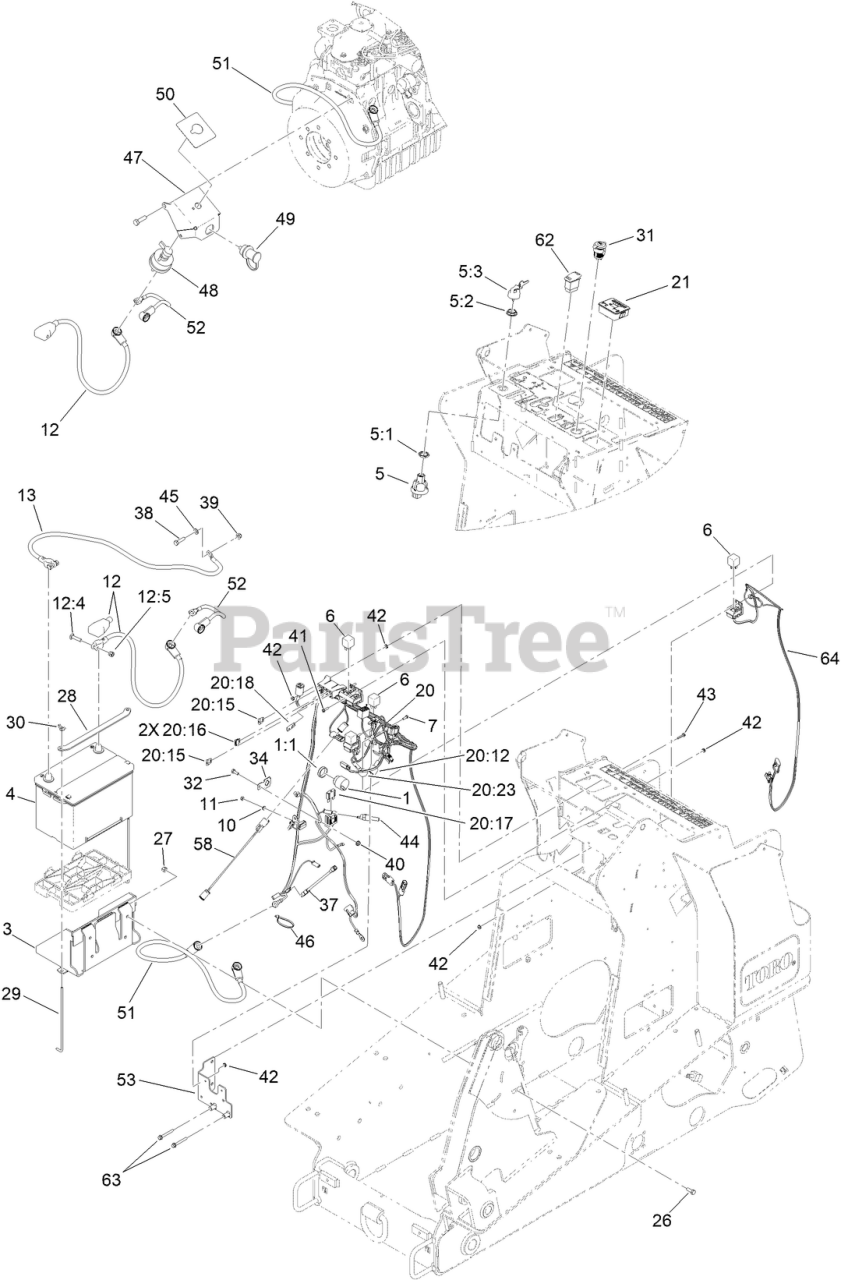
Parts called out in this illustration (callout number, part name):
1	AUDIO ALARM ASM
1:1	NUT-PLASTIC, KNURLED
3	TRAY-BATTERY
4	BATTERY
5	IGNITION SWITCH ASM
5:1	NUT-HEX
5:2	NUT-FACE, M22 (PLASTIC)
5:3	SET-KEY, IGNITION
10	WASHER-LOCK, SPRING
11	NUT-HEX
12	CABLE-BATTERY, POS ASM
12:4	BOLT-BATTERY CLAMP, 5/16-18 UNC
12:5	NUT-CLAMP, BATTERY
13	CABLE-NEGATIVE
20	HARNESS-WIRE, MAIN
20:15	FUSE-BLADE, 10 AMP
20:16	FUSE-BLADE, 15 AMP
20:17	FUSE-BLADE, 50 AMP
20:18	CAP-PLUG
21	MODULE-HOUR METER
26	SCREW-HH
27	NUT-LOCK, NI
28	STRAP-HOLD DOWN, BATTERY
29	ROD-HOLD DOWN, BATTERY
30	NUT-WING
31	RECEPTACLE-12V
32	SCREW-HH
34	CLIP-FUSE
37	HARNESS-LINK, FUSIBLE
38	SCREW-HH
39	NUT-HF, NI
40	NUT-HF
41	SCREW-HWH
42	NUT-KEPS
43	SCREW-HWHTF
44	SWITCH-TEMP
45	WASHER-PLAIN
46	TIE-CABLE
47	MOUNT-REMOTE TERMINAL
48	SWITCH-DISCONNECT, MASTER
49	STUD-JUMPER, POSITIVE
50	DECAL-BATTERY DISCONNECT
51	CABLE-BATTERY, POSITIVE
52	CABLE-BATTERY, POSITIVE
58	HARNESS-WIRE
62	SWITCH-ROCKER, ON-NONE-(ON)
63	SCREW-HHF
64	HARNESS-WIRE, AUX HOLD
